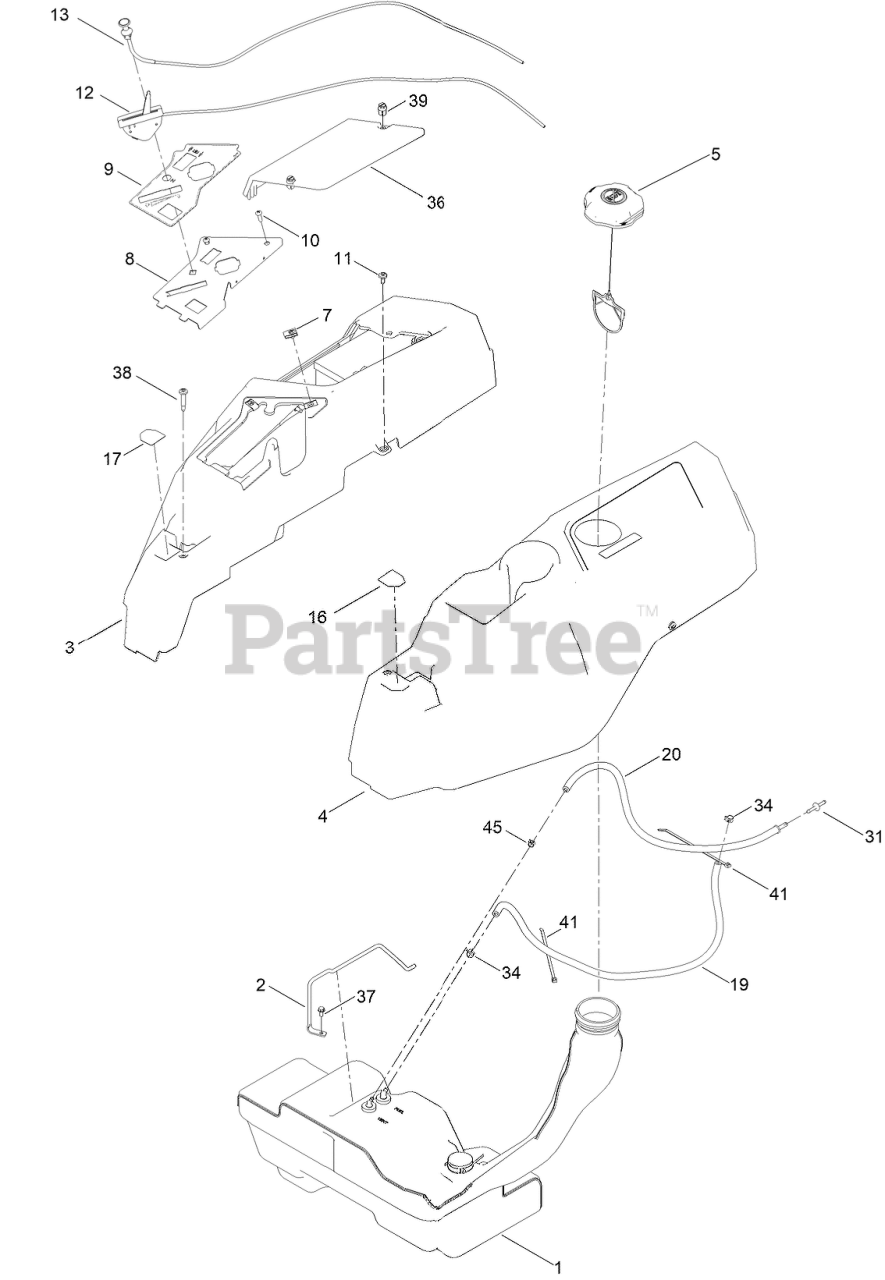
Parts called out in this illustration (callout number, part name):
1	TANK-FUEL ASM
2	ROD-HOLD DOWN
3	POD-RH
4	POD-LH
5	CAP-FUEL, RATCHETING
8	PANEL-CONTROL
9	DECAL-PANEL, CONTROL
10	SCREW-PRH
11	SCREW-SHOULDER
12	CABLE-THROTTLE
13	CABLE-CHOKE
16	DECAL-LEVER, CONTROL (LH)
17	DECAL-LEVER, CONTROL (RH)
19	HOSE-FUEL
20	HOSE-VENT
31	ADAPTER ORIFICE
34	CLAMP-HOSE
36	COVER-BATTERY
37	SCREW-HWH
38	SCREW-SHOULDER
39	FASTENER
41	TIE-CABLE
45	CLAMP-HOSE
